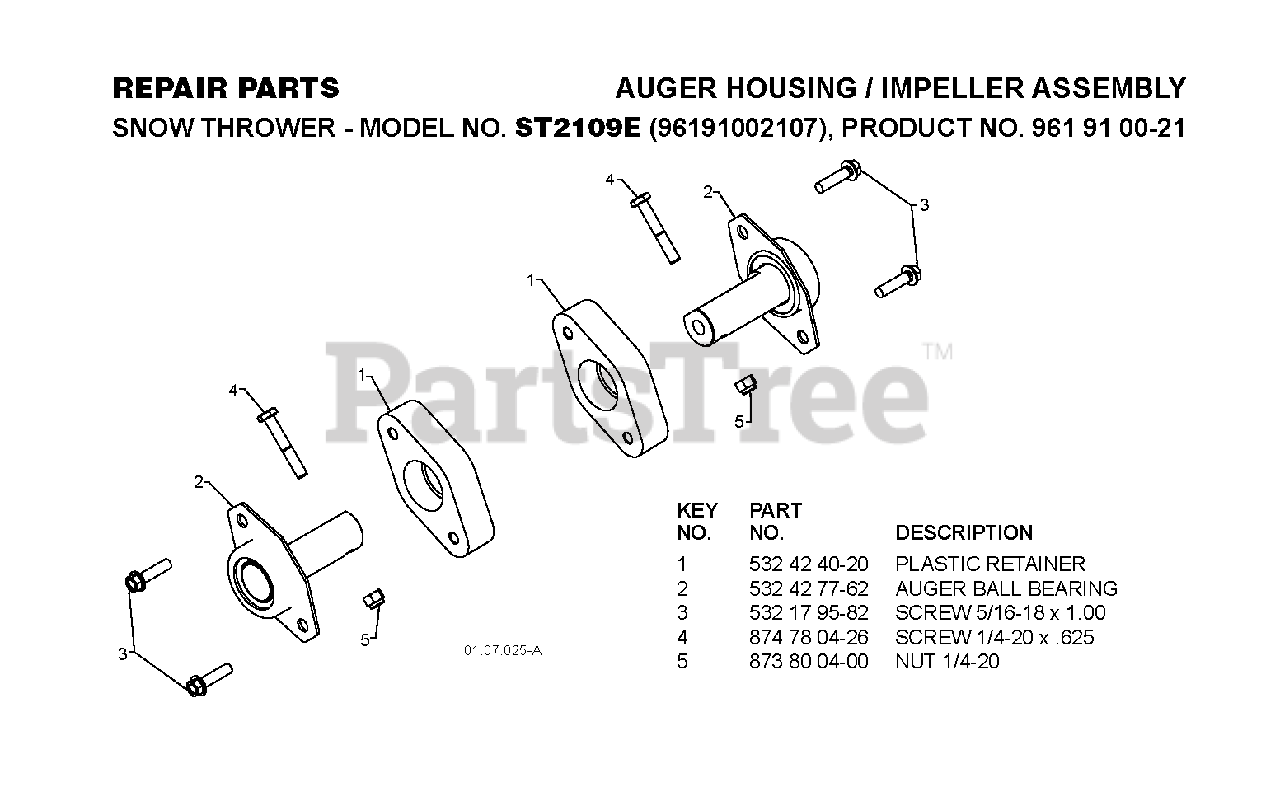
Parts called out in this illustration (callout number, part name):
1	RETAINER.PLASTIC
2	RP BEARING.BALL.AUGER.FLAT.
3	SCREW, HEX HD 5/16X1
4	SCREW.HEX.HD1/4-20X
5	LOCKNUT
